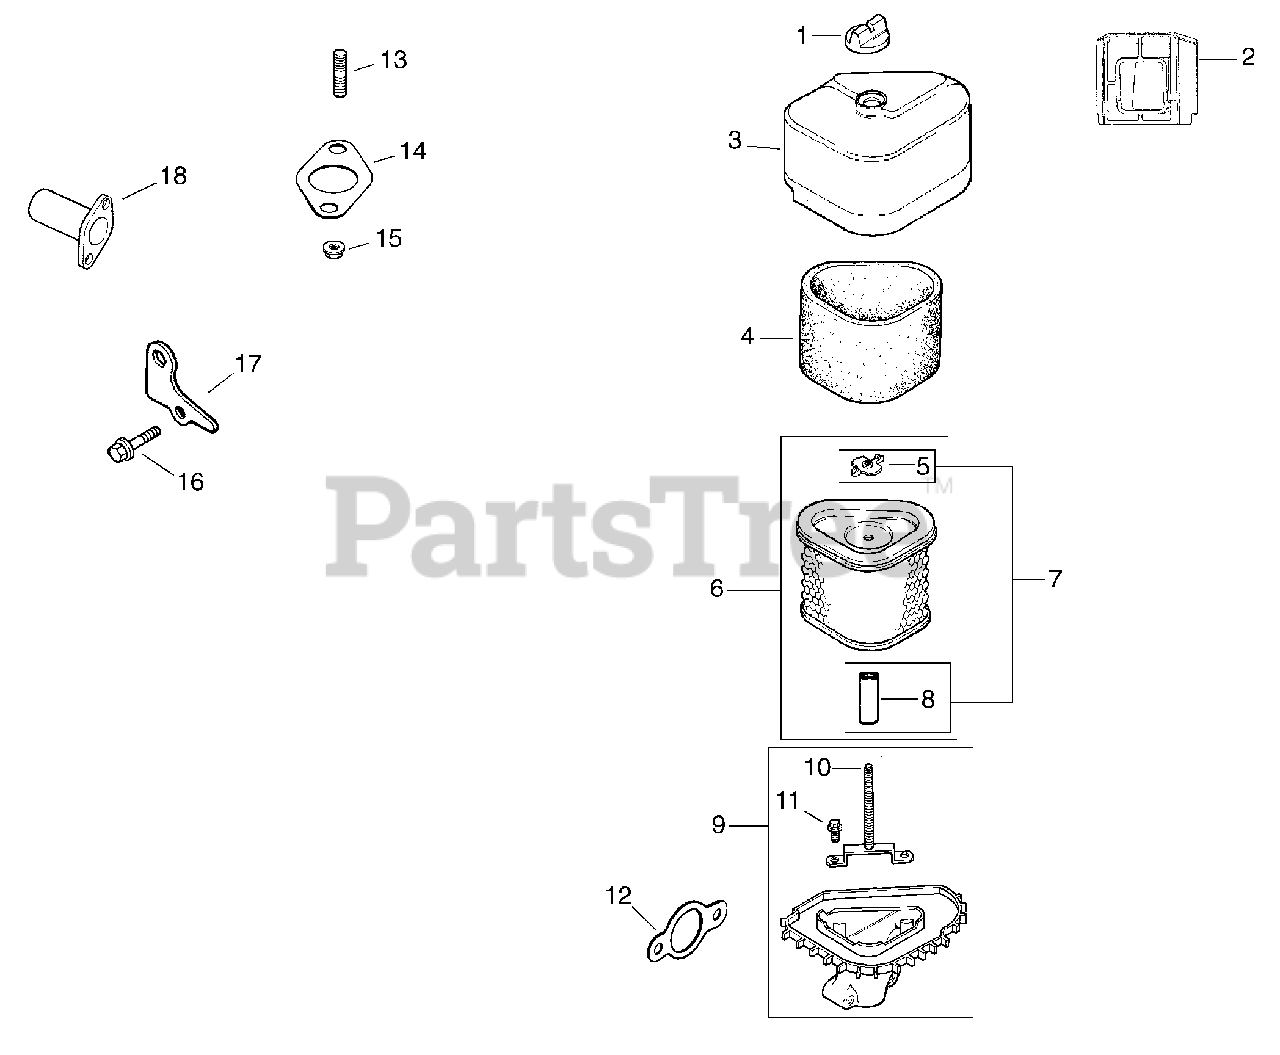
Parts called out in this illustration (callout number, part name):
1	Knob, Air Cleaner Cover
2	Duct, Air (Model 1517)
3	Cover, Air Cleaner
4	Precleaner
6	Element, Air Cleaner
7	Kit, Air Cleaner Seal
9	Base, Air Cleaner
10	Stud M6 x 1.0 x 79
11	Screw, #10 Hi-Lo Thread Forming
12	Gasket, Air Cleaner
13	Stud M8 x 1.25 x 39
14	Gasket, Exhaust Manifold
15	Nut, Hex. Flange M8 x 1.25
16	Screw, Hex. Flange M6 x 1.0 x 25
17	Strap, Lifting
